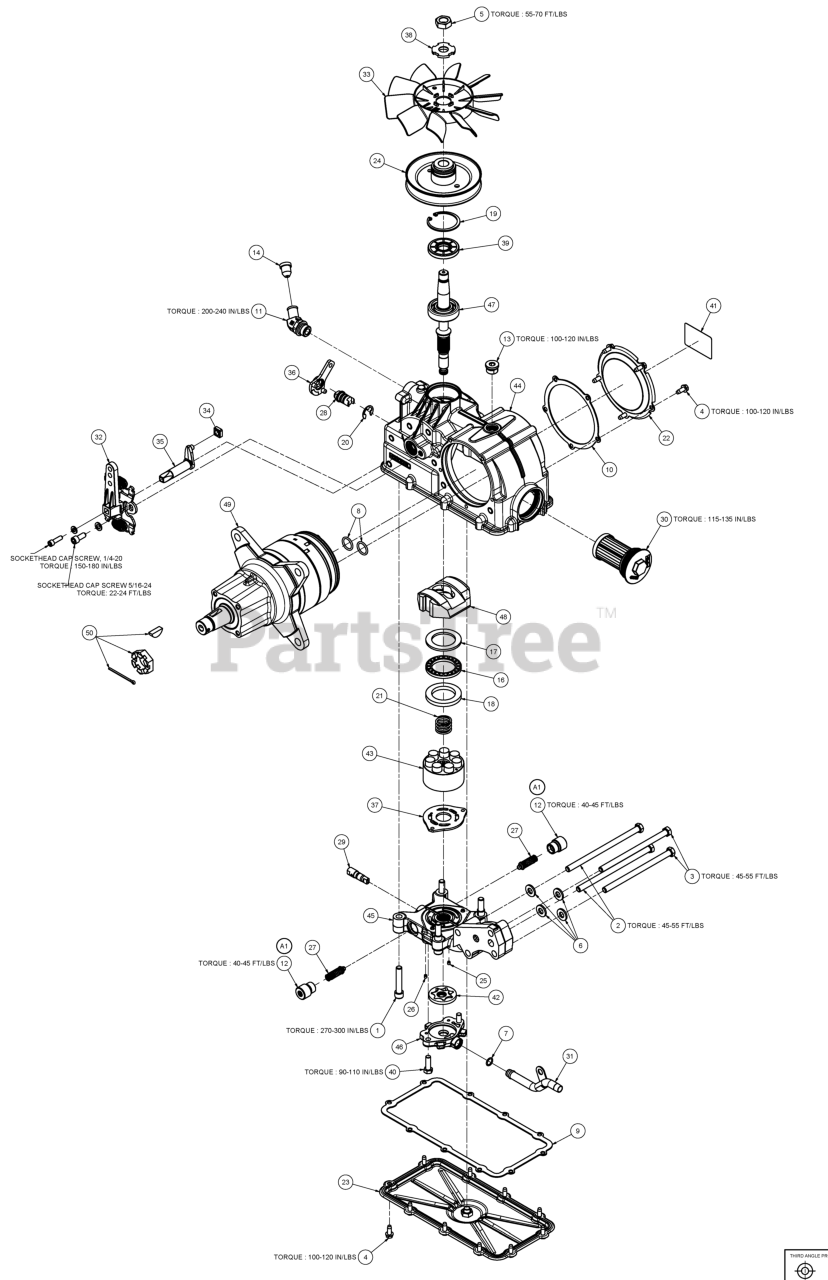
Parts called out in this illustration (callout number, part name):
5	NUT CHART
6	FLAT WASHER
7	PACKING PREFORMED O-RING SEAL
8	PACKING PREFORMED O-RING SEAL
9	GASKET BOTTOM COVER FE
10	GASKET SIDE COVER
11	FITTING, 45° BEADED HOSE BARB (SAE STE THD 3/4-16)
12	PLUG & O-RING ASSEMBLY
13	HOLLOW HEX VENT PLUG ASSEMBLY
14	PLUG, RUBBER
16	THRUST BEARING
18	WASHER, THRUST
19	INTERNAL RETAINING RING (SHAFT SEAL)
20	RETAINING RING
21	SPRING (CENTRAL)
22	SIDE COVER
23	SA, BOTTOM COVER
24	PULLEY, TAPERED
25	ORIFICE PLUG (Ø .031)
27	RELIEF VALVE SUB-ASSEMBLY
28	SA, BYPASS
29	S/A, CHARGE RELIEF
30	TRANSMISSION OIL FILTER
31	FILTER TUBE (LH)
32	SA, RTN (LH) STANDARD SPRING
33	FAN KIT
34	CONTROL BLOCK
35	TRUNNION ARM, MACHINED
37	PORT PLATE
38	SPACER,FAN
39	SEAL, SHAFT
40	SCREW, HEX HEAD UNRF
41	LABEL
42	ROTOR SET ASSEMBLY
44	TOP HOUSING ASSEMBLY
45	END BLOCK ASSEMBLY (LH)
46	COVER - CHARGE PUMP
47	SA, SHAFT
48	SA, SWASH BLOCK
49	SA, MOTOR
50	SERVICE KIT NUT, COTTER PIN & KEY
